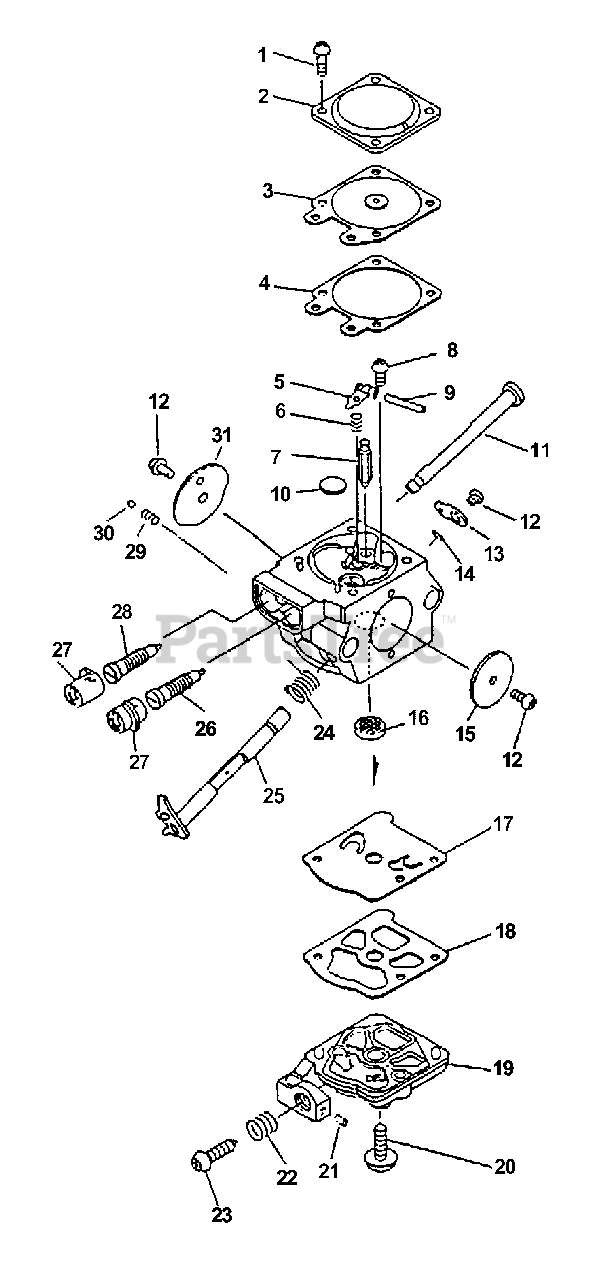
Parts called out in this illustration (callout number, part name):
1	SCREW
2	COVER, METERING
3	DIAPHRAGM, METERING
4	GASKET, METERING
5	LEVER, METERING
6	SPRING, METERING LEVER
7	VALVE, INLET NEEDLE
8	SCREW, METERING LEVER PIN
9	PIN, METERING LEVER
10	PLUG, WELCH
11	SHAFT, CHOKE
13	LEVER, THROTTLE
14	RING, RETAINING
15	VALVE, THROTTLE
16	STRAINER
17	DIAPHRAGM, PURGE
18	GASKET, PURGE
19	COVER, PUMP
20	SCREW, PUMP COVER
22	SPRING, IDLE ADJUST
23	SCREW, IDLE ADJUST
24	SPRING, THROTTLE RETURN
25	SHAFT, THROTTLE
26	NEEDLE - LOW SPEED
27	CAP, LIMITER
28	NEEDLE - HIGH SPEED
30	BALL, CHOKE
31	VALVE, CHOKE
